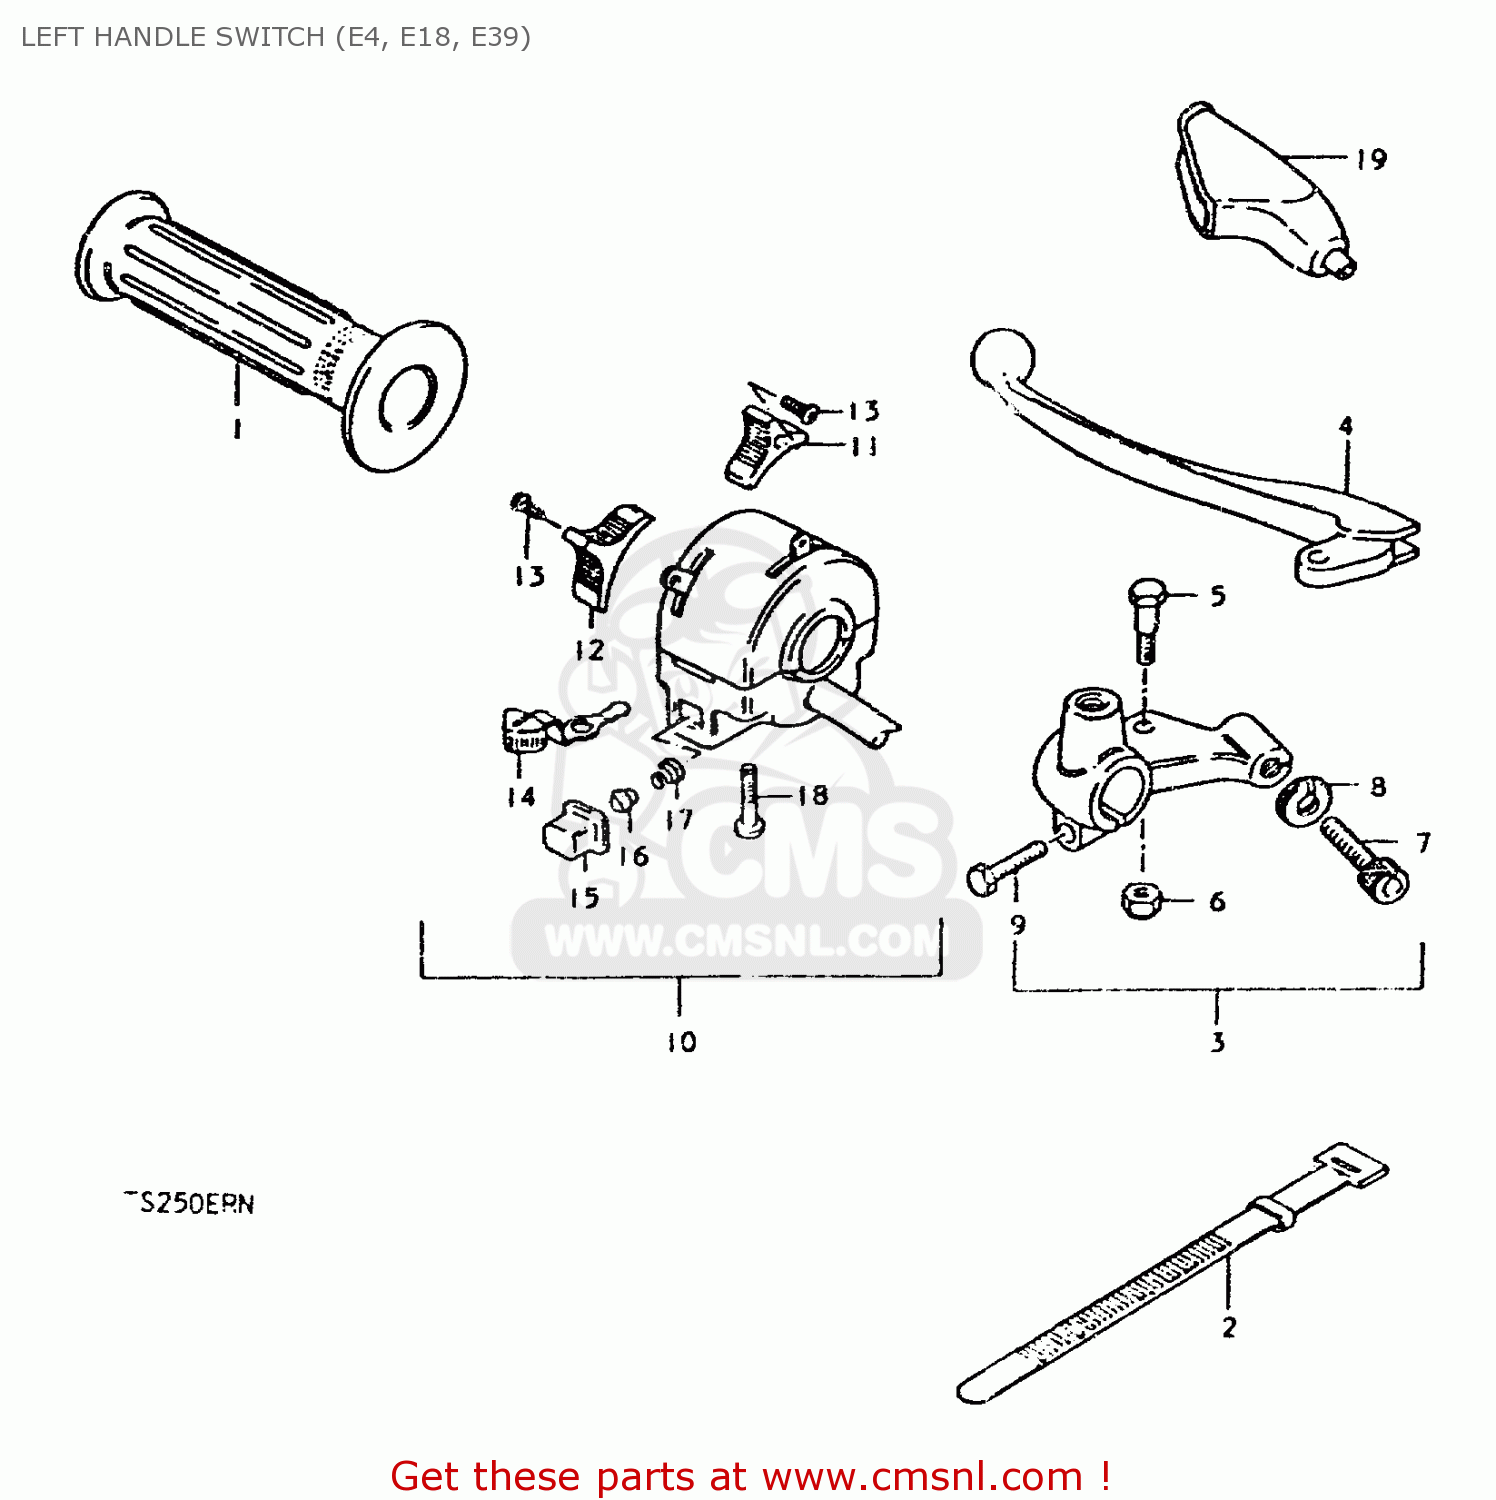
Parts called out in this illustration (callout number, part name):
1	GRIP,L
2	CLAMP(L:120)
3	LEVER ASSY,CLUTCH
4	LEVER,CLUTCH
5	BOLT,LEVER
6	NUT 6MM
7	ADJUSTER,CABLE
8	NUT,CABLE ADJUSTER
9	BOLT
10	SWITCH ASSY,HANDLE,L
11	KNOB,LIGHTING SWITCH
12	KNOB,DIMMER SWITCH
13	SCREW
14	KNOB,TURNSIGNAL
15	BUTTON,HORN
16	CONTACT
17	SPRING
18	SCREW
19	COVER,CLUTCH LEVER
